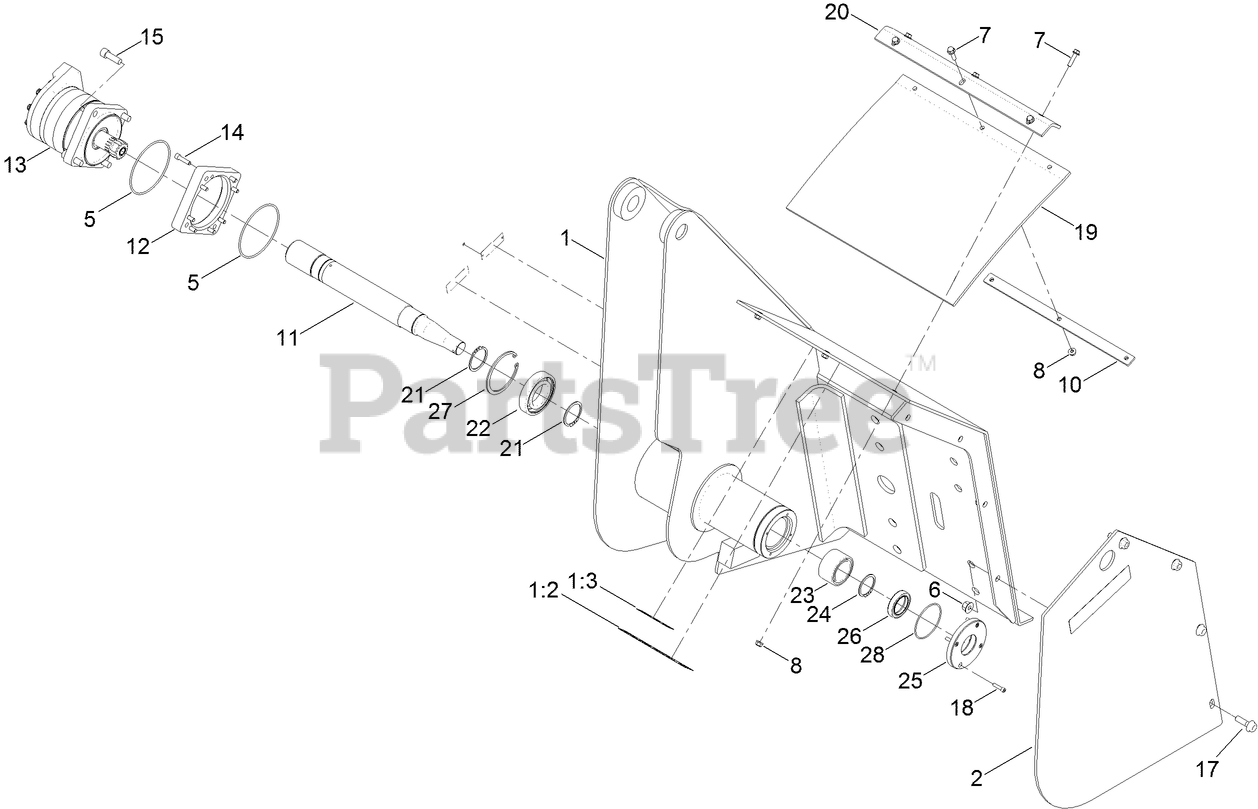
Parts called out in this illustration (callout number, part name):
1	FRAME-TRENCHER
1:2	DECAL-DANGER, ENTANGLEMENT
1:3	DECAL-DANGER
2	SIDE PLATE
5	O-RING
6	NUT-LOCK, HHF
7	SCREW-HHF
8	NUT-HF
10	STRIP-DEFLECTOR, DIRT
11	SHAFT-DRIVE
12	FLANGE-MOTOR
13	MOTOR-HYDRAULIC, VIS 40
14	SCREW-HSH
15	SCREW-HSH
18	SCREW-HSH
19	DEFLECTOR-DIRT
20	ANGLE-DIRT DEFLECTOR
21	RING-RETAINING, SNAP
22	BEARING-BALL, 55MM
23	BEARING-CARB, 50MM
24	RING-SNAP, 50MM
25	PLATE-HOLDER, SEAL
26	SEAL-CRWA5, 2.50
27	RING-SNAP, 100MM
28	O-RING
